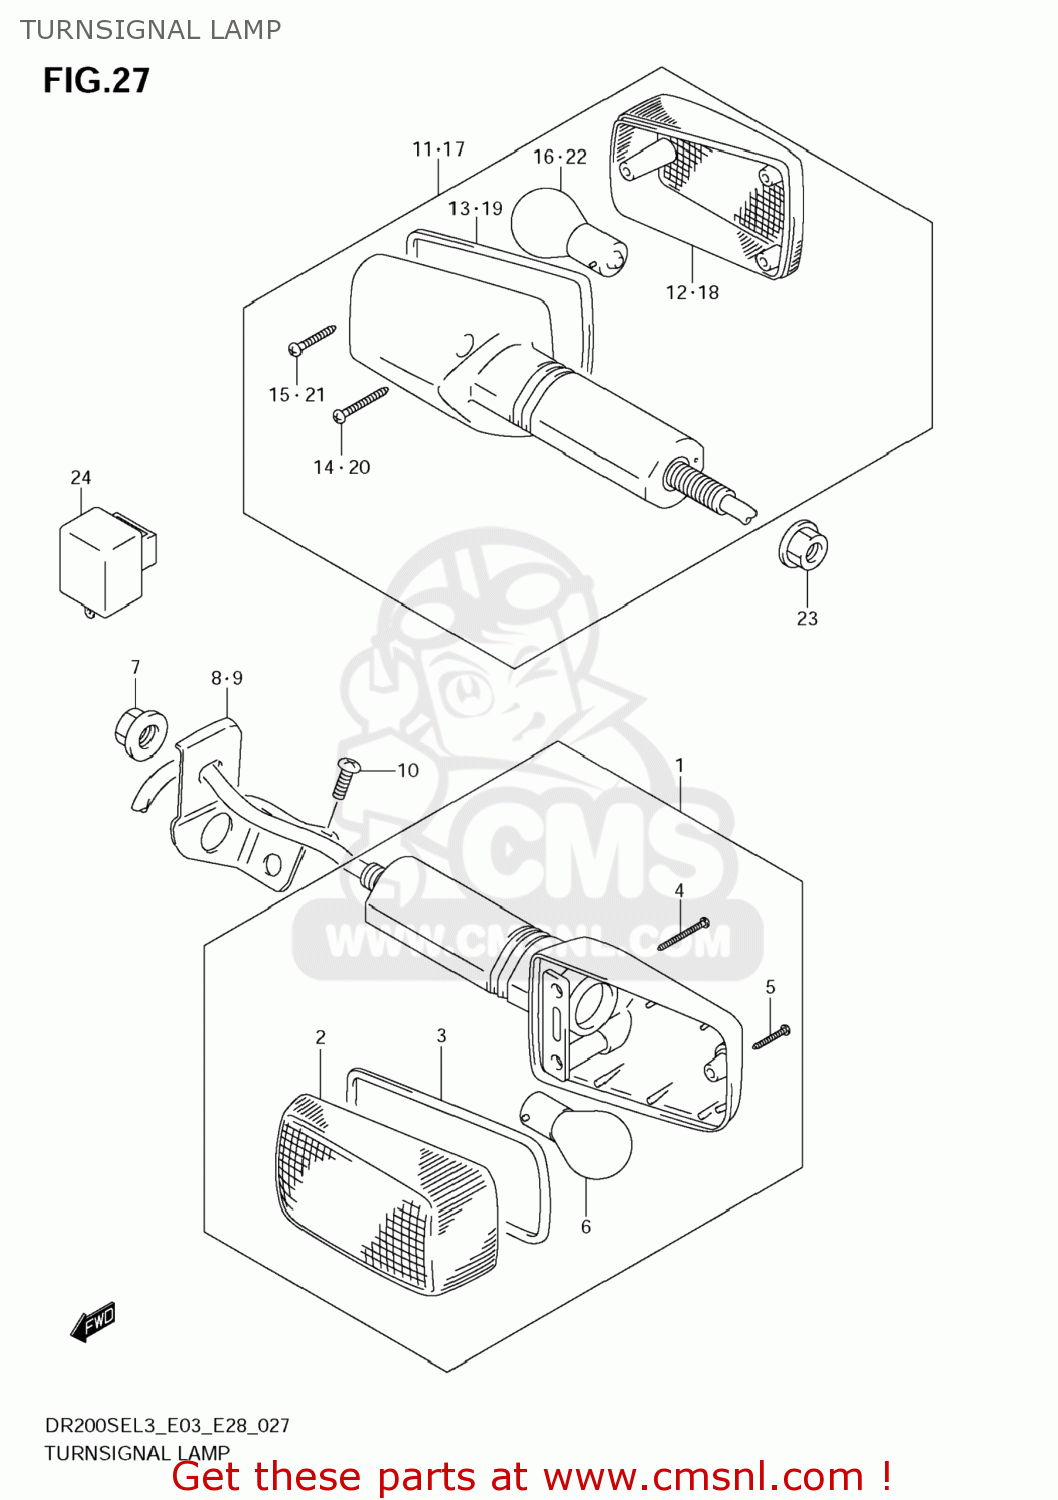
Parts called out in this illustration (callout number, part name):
1	LAMP ASSY,FR TURN SIGNAL
2	LENS
3	GASKET (NAS)
4	SCREW(3X30)
5	SCREW
6	BULB(12V21W)
7	NUT
8	BRACKET,FR TURN,R
9	BRACKET,FR TURN,L
10	SCREW
11	LAMP ASSY,RR TURNSIGNAL
12	LENS
13	GASKET (NAS)
14	SCREW(3X30)
15	SCREW
16	BULB(12V21W)
17	LAMP ASSY,RR TURNSIGNAL
18	LENS
19	GASKET (NAS)
20	SCREW(3X30)
21	SCREW
22	BULB(12V21W)
23	NUT
24	RELAY ASSY,TURNSIGNAL
